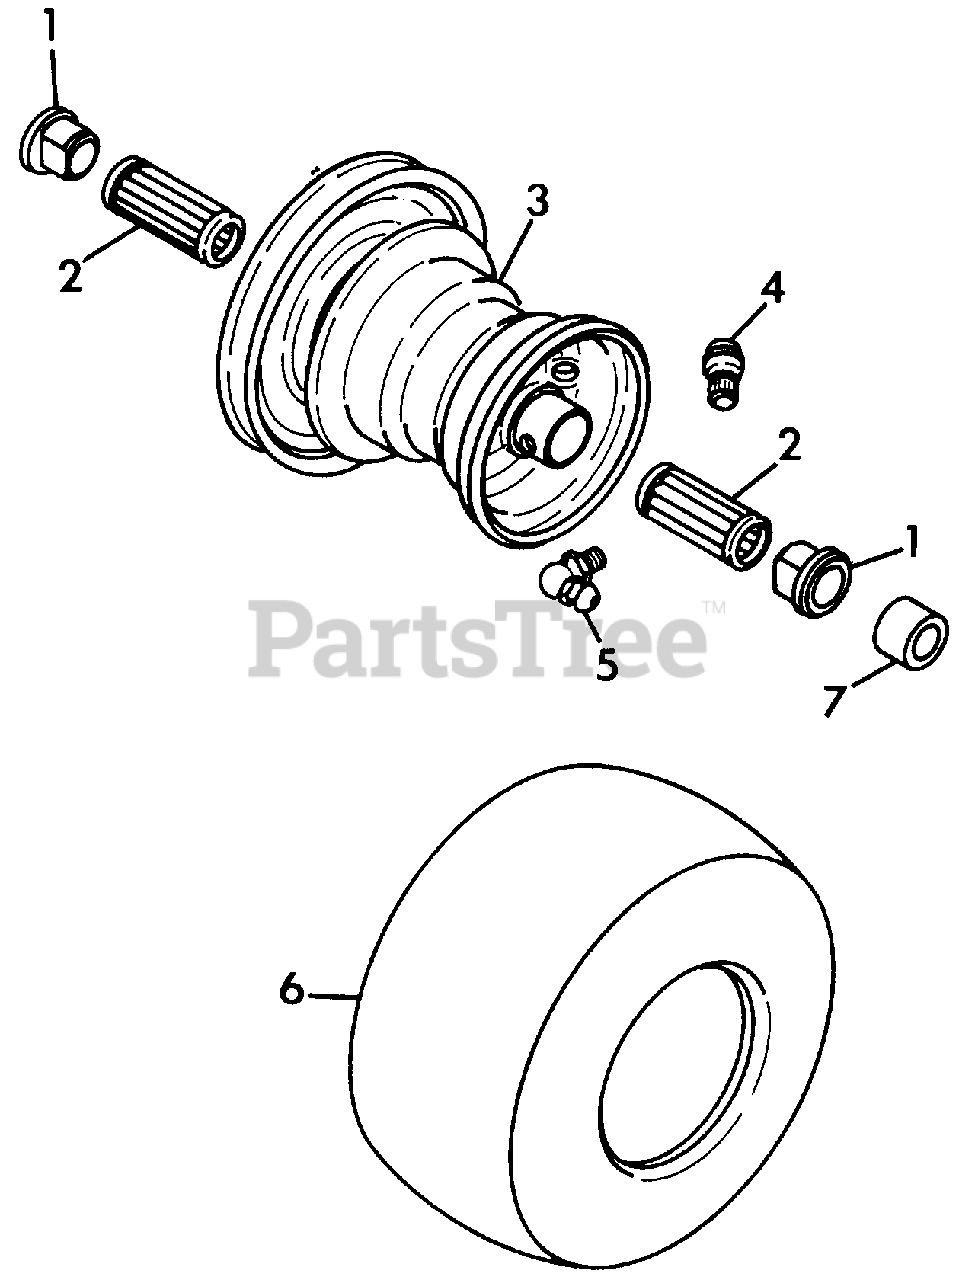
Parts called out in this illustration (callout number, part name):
1	BEARING, FLANGE
2	BEARING, 7/8X2.00
3	RIM
4	ASSEMBLY, VALVE STEM
5	FITTING, LUBE 90 DEG.
6	TIRE, 13X5.00-6
7	SPACER
NS	ASSEMBLY, WHEEL 13X5.00-6
